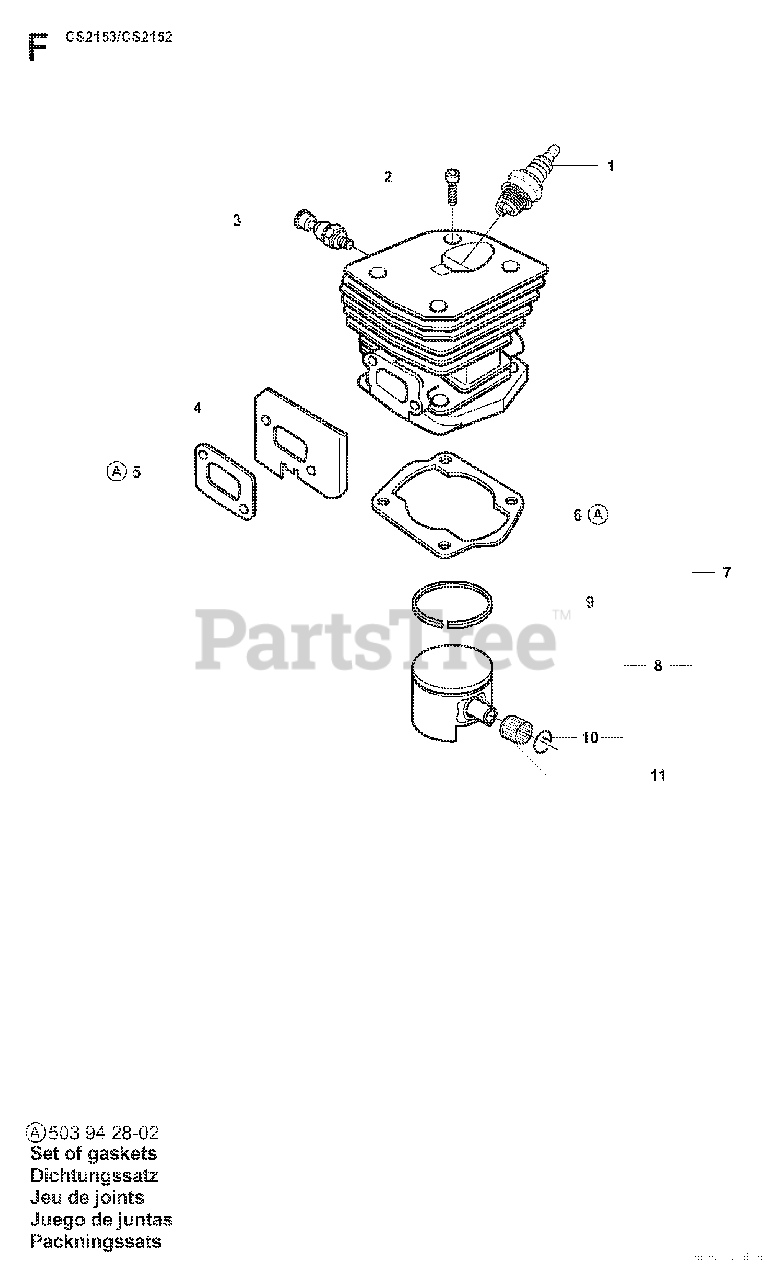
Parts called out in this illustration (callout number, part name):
1	SPARK PLUG RCJ7Y
2	SCREW MC6S 5X25
3	DECOMPRESSION VALVE
7	%CYLINDER
8	%PISTON
9	PISTON RING
10	LOCKING RING
11	RP SUPPORT BUSHING
A	GASKET SET
